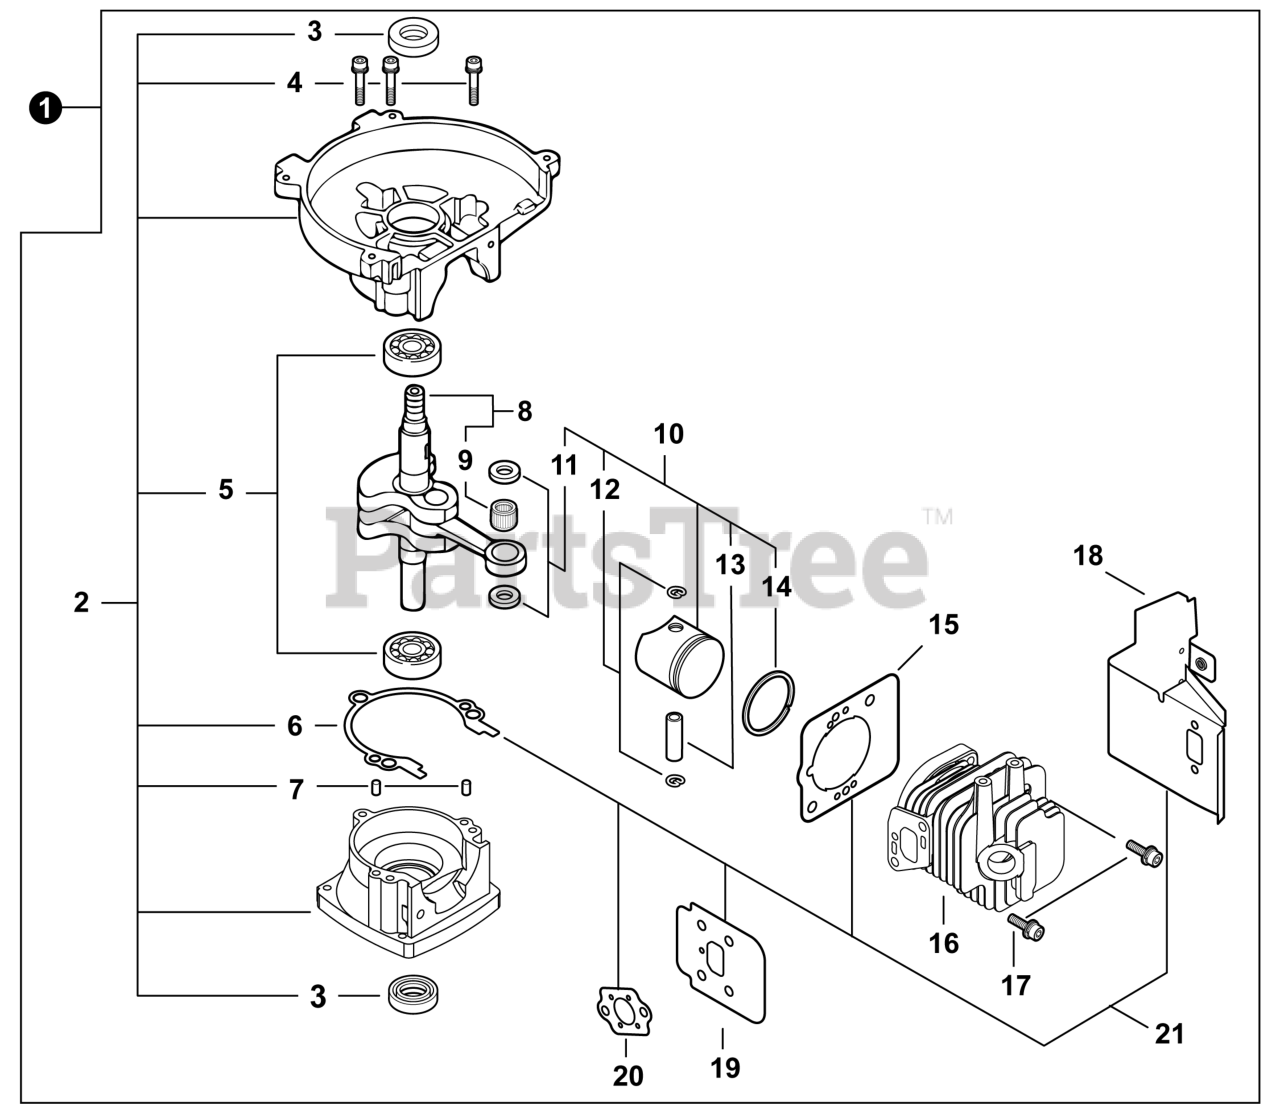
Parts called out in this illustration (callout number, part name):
1	SHORT BLOCK
2	CRANKCASE KIT
3	SEAL, OIL 12
4	BOLT 5x28
5	BEARING, BALL 6201
6	GASKET, CRANKCASE
7	PIN, LOCATING 4x8
8	CRANKSHAFT ASSY
9	BEARING, NEEDLE 8
10	PISTON KIT
11	WASHER, THRUST
12	RING, SNAP
13	PIN, PISTON 8
14	RING, PISTON
15	GASKET, CYLINDER
16	CYLINDER
17	BOLT 5x22
18	HEAT SHIELD, EXHAUST
19	HEAT SHIELD, INTAKE
20	GASKET, INTAKE
21	GASKET KIT: ENGINE, INTAKE, EXHAUST
